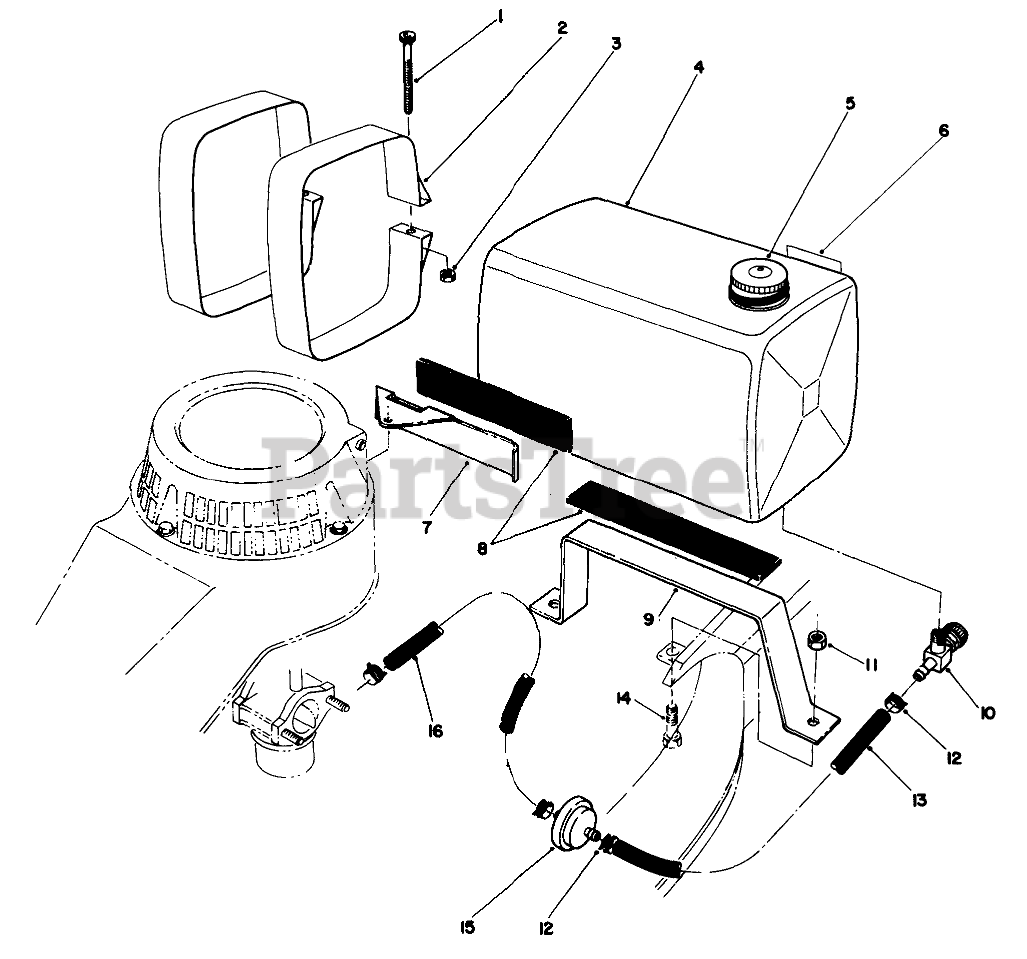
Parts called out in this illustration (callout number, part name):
1	SCREW-HSH
2	TANK MTG STRAP WA
3	NUT-HEX
4	Tank-Gas (Incl. Ref. #5)
5	CAP CAP
6	FUEL TANK DECAL
7	FRT TANK MOUNT
8	ISOLATOR PAD
9	BOTTOM TANK MOUNT
10	.125 ID SHUTOFF VALVE
11	NUT-LOCK, NI
12	CLAMP-FUEL LINE
13	LINE-GAS
14	SCREW-HH
15	FILTER-FUEL
16	HOSE-FUEL
